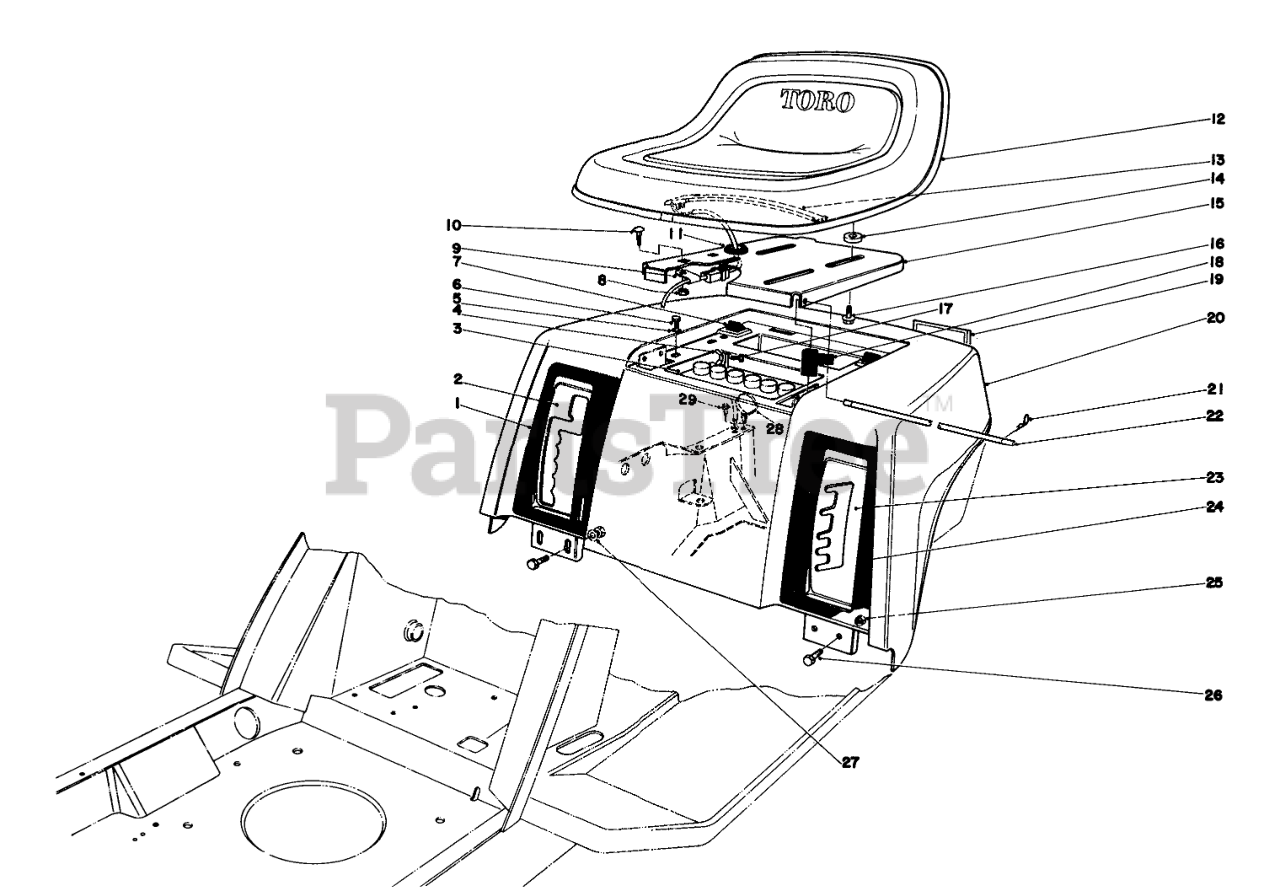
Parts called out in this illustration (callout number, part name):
1	Decal-Transmission
2	DETENT PLATE B
3	Battery
4	NUT-WING
5	WASHER
6	SCREW-HWHTF
7	SEAT BUMPER
8	NUT-KEPS
9	CLAMP
10	SCREW-CARR
11	GROMMET
13	SWITCH-SEAT
14	SPACER-PIN, MOUNTING
15	SEAT SUPPORT R
16	SCREW-HHF
17	SCREW-HH
18	BOOT-TERMINAL
19	REFLECTOR
20	Rear Body (Incl. Ref. #1 & 24)
21	PIN-COTTER
22	PIVOT-SEAT
23	Quadrant Height of Cut
24	Decal Height of Cut
25	NUT-LOCK, CONE
26	SCREW-HH
27	WASHER-PLAIN
28	TIE-MOUNT, PUSH
29	SCREW-HWHTF
